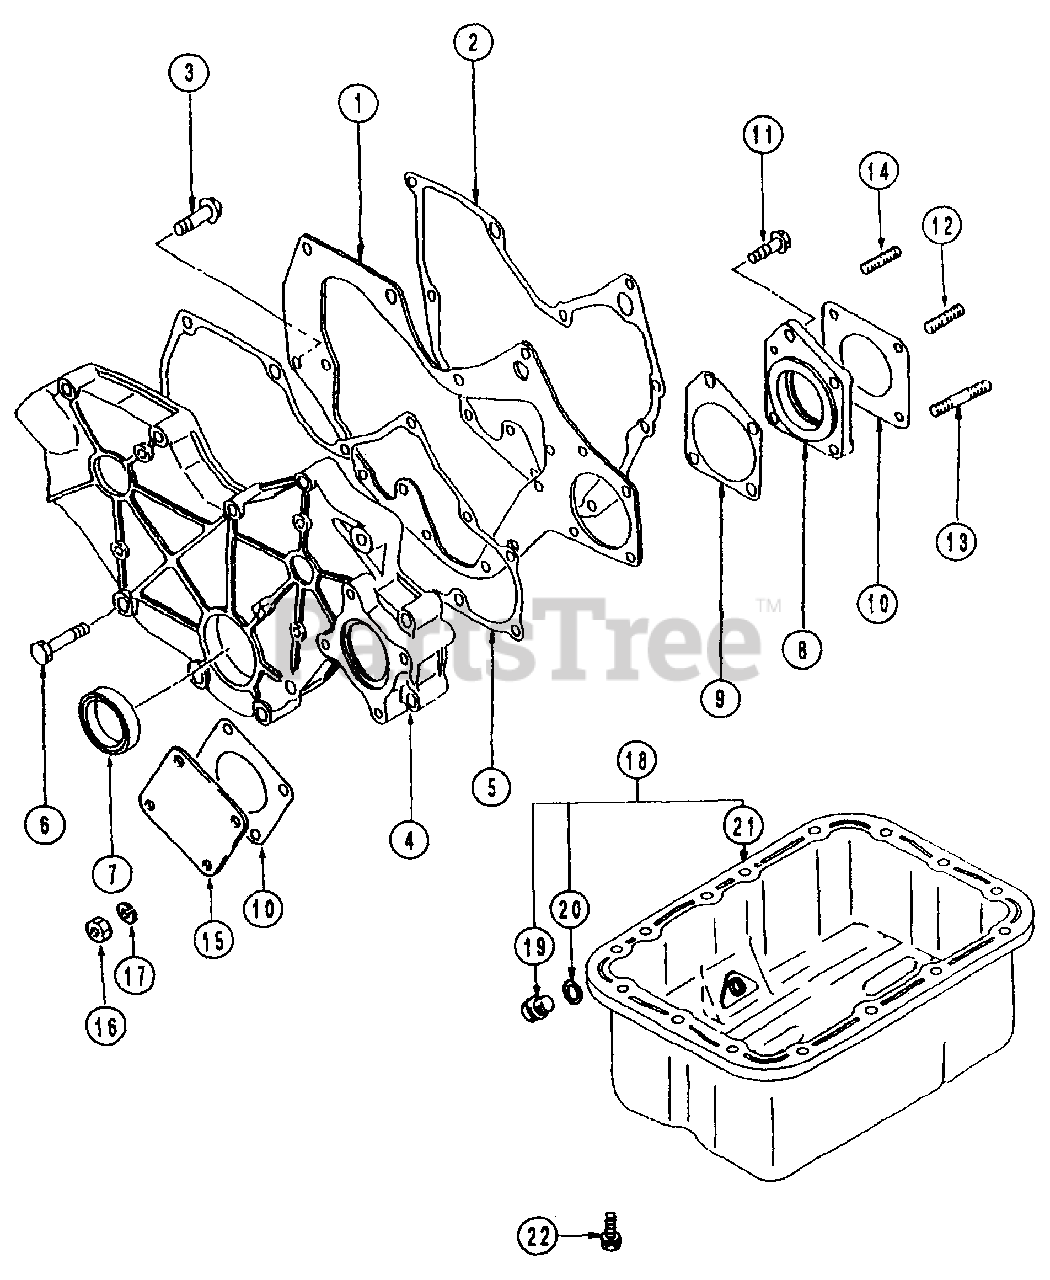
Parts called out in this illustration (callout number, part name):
2	Gasket, Front Plate
3	Bolt, W/Washer
4	Case, Gear, PTO
5	Gasket, Gear
8	Housing, Gear Pump
9	Gasket, Housing
10	Gasket, O/Pump Cover
11	Bolt, W/Washer
12	Stud
15	Cover,Oil Pump
17	Washer, Spring
18	Pan Ass'y., Oil
20	Gasket,Oil Drain
21	Pan, Oil
22	Bolt, W/Washer
